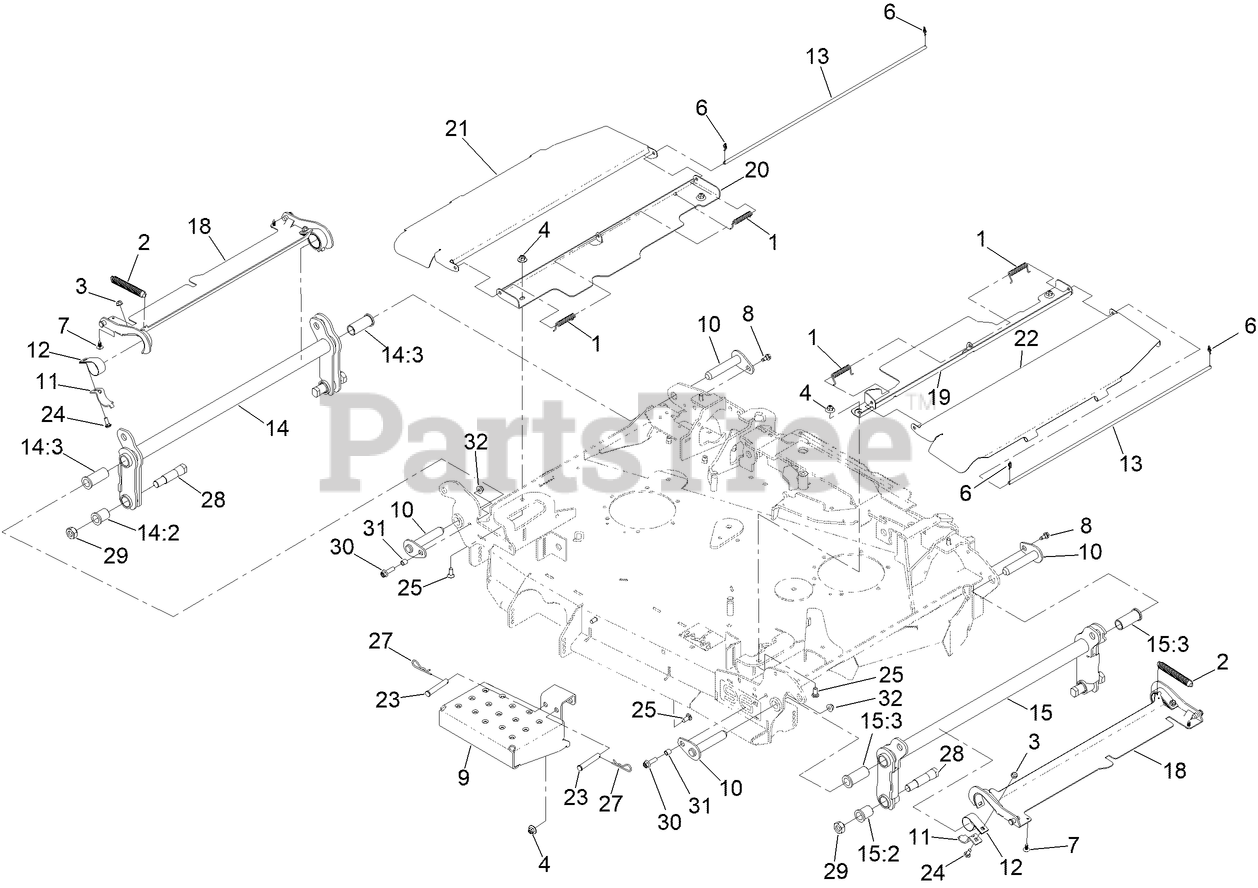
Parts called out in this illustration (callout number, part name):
1	SPRING-TORSION
2	SPRING
3	NUT-HF, NI
4	NUT-FLANGE, NI
6	PIN-COTTER, LOCKING
7	PLUG-PLASTIC
8	SCREW-SHOULDER
9	PLATE-STEP
10	ASM-DECK PIN
11	PLATE-RETAINER, BEARING
12	BEARING-STRAP, NYLON
13	COVER-ROD, PIVOT
14	ASM-RH FOLD ARM
14:2	BUSHING-FLANGED
14:3	BUSHING-FLANGE
15	ASM-LH FOLD ARM
15:2	BUSHING-FLANGED
15:3	BUSHING-FLANGE
18	COVER-WING
19	SHIELD-CENTER, LH
20	SHIELD-CENTER, RH
21	PANEL-SHIELD HINGE, RH
22	PANEL-SHIELD HINGE, LH
23	PIN-CLEVIS
24	SCREW-CARR
25	BOLT-CARR
27	PIN-HAIR
28	BOLT-PIVOT PIN
29	NUT-LUG
30	SCREW, HHF
31	SPACER-TUBE, PUMP LINK
32	NUT-HF, NI
